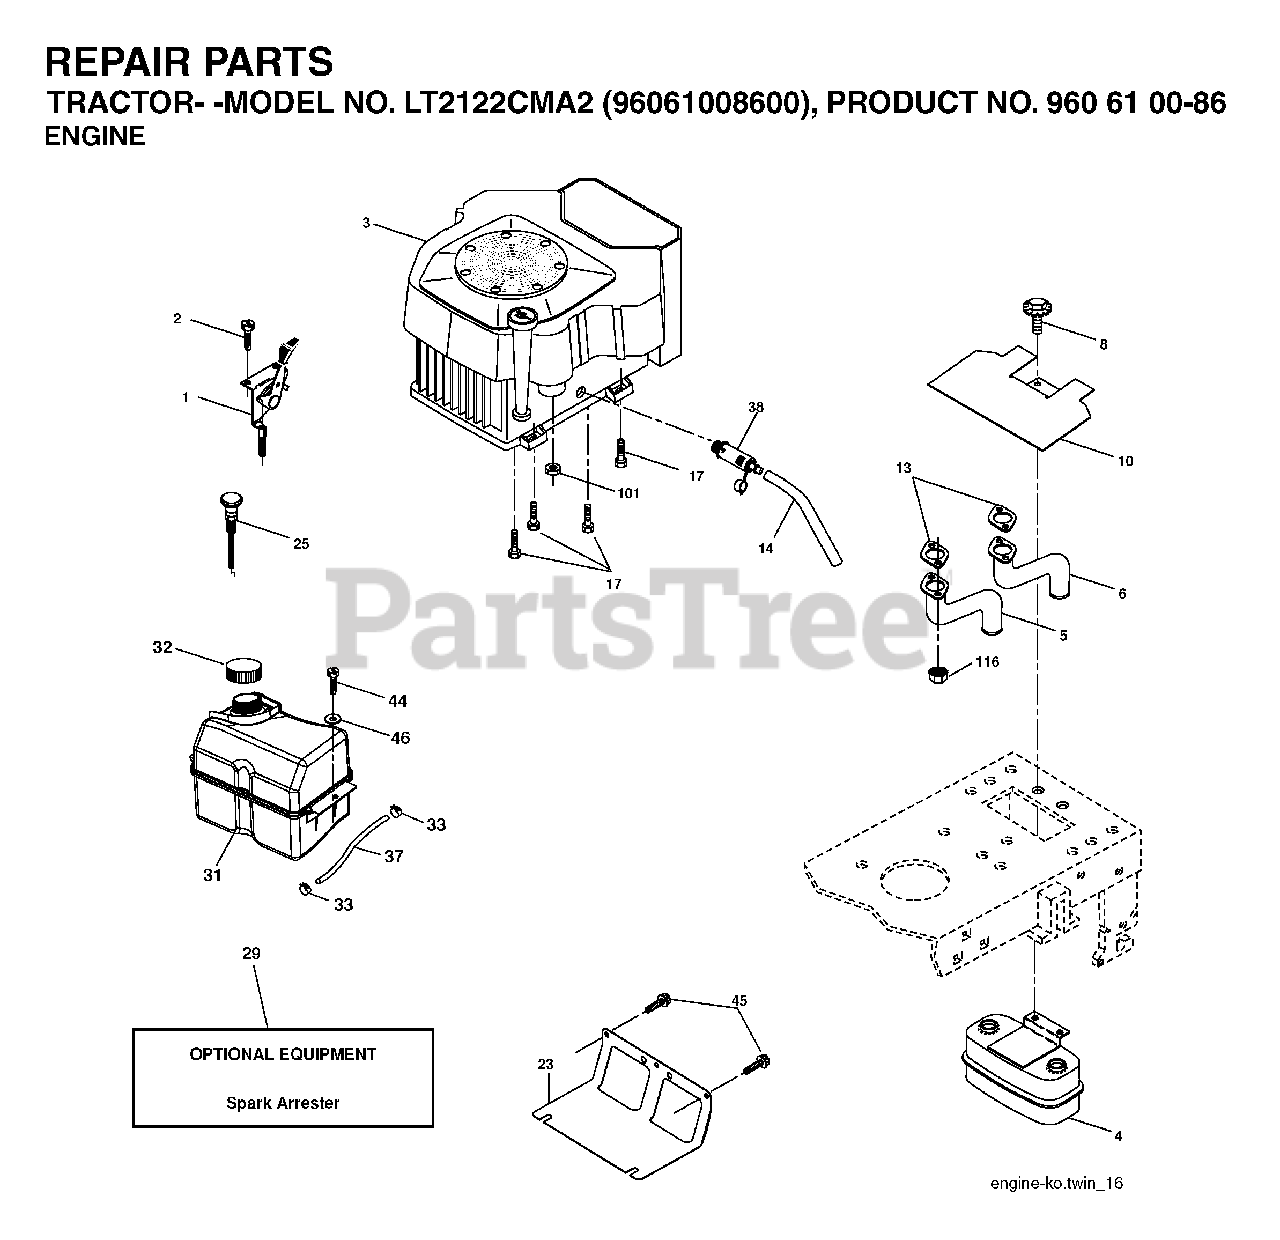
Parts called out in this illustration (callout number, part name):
1	CONTROL.THROTTLE.KAWA
2	SCREW
4	MUFFLER.TWIN.CYL.LOW.TONE
5	PIPE-EXHAUST LH
6	PIPE-EXHAUST RH
8	BOLT, 5/16-18 X 1 3/4
10	RP SHIELD HEAT MUFFLER
14	TUBE, DRAIN OIL ASM.
23	SHEILD.BROWNING.DBR.GUARD
25	CONTROL, CHOKE
29	ARRESTER SPARK (OPTIONAL)
31	TANK FUEL
32	FUEL CAP
33	HOSE CLAMP
37	LINE.FUEL.20
38	PLUG DRAIN OIL EASY
44	SCREW HEXWSHR 1/4-20X3/4
45	SCREW, 3/8-16X3/4
101	FLANGE NUT
116	NUT.HEX.FLANGE.TOPLOCK
